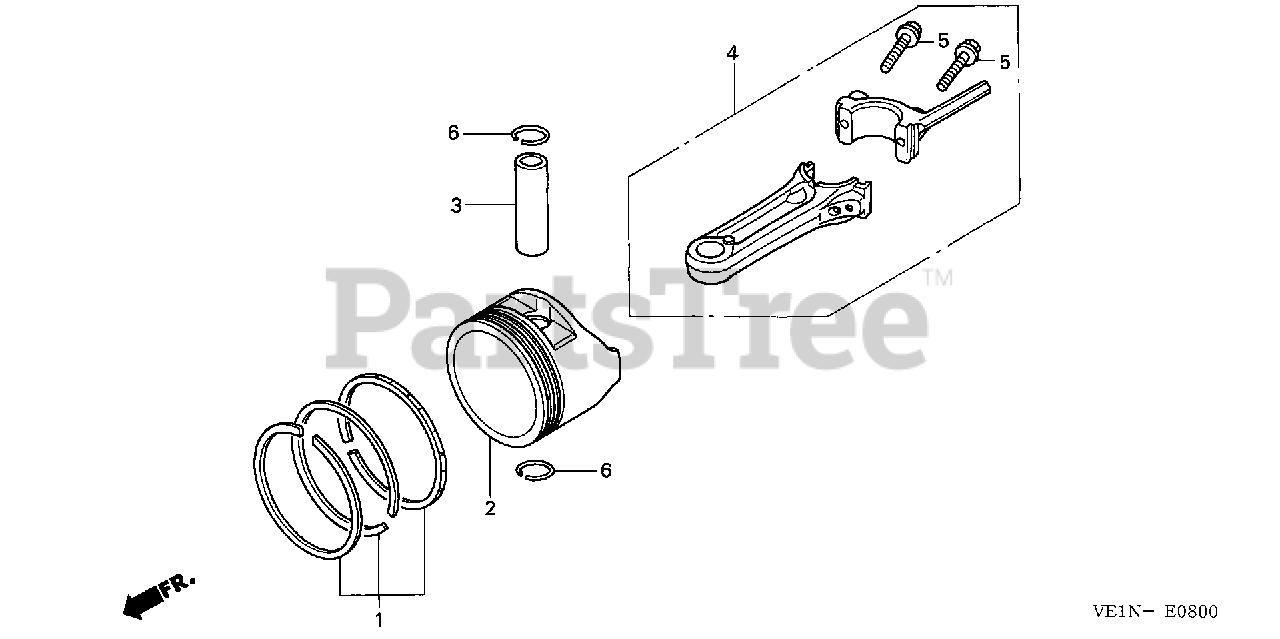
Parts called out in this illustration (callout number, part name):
1	RING SET, PISTON (STD) (TEIKOKU)
3	PIN, PISTON
4	ROD ASSY., CONNECTING
5	BOLT, CONNECTING ROD
6	CLIP, PISTON PIN (13MM)
